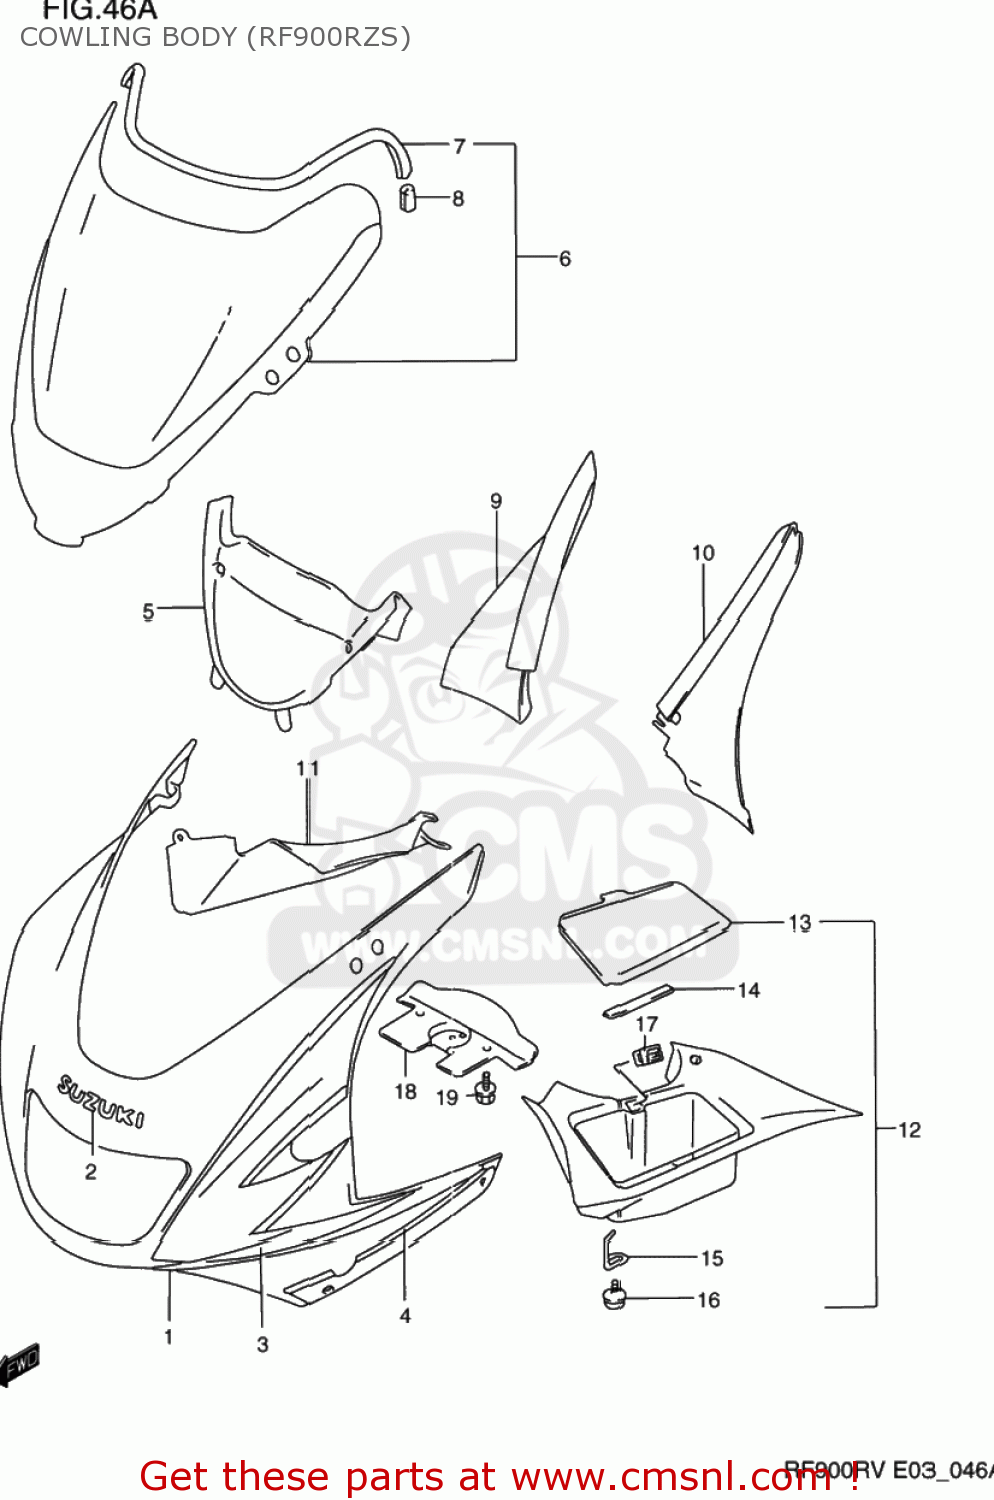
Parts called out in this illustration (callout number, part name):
1	COWLING ASSY,BODY(PURPLE)
2	EMBLEM,COWLING UPR
3	TAPE SET,COWL BODY FR
4	TAPE SET,COWL BODY SIDE
5	PANEL,COWLING CTR
6	WINDSCREEN SET
7	MOLDING WINDSCREEN
8	CLIP,WINDSCREEN MOLDING
9	PANEL,UPR,R
10	PANEL,UPR,L
11	PANEL,SIDE,R
12	PANEL ASSY,SIDE,L
13	LID,PANEL BOX
14	CUSHION,LID
15	HINGE,PANEL LID
16	SCREW
17	LOCK,I/P CTR BOX
18	COVER,COWLING FR LWR
19	BOLT(6X12)
